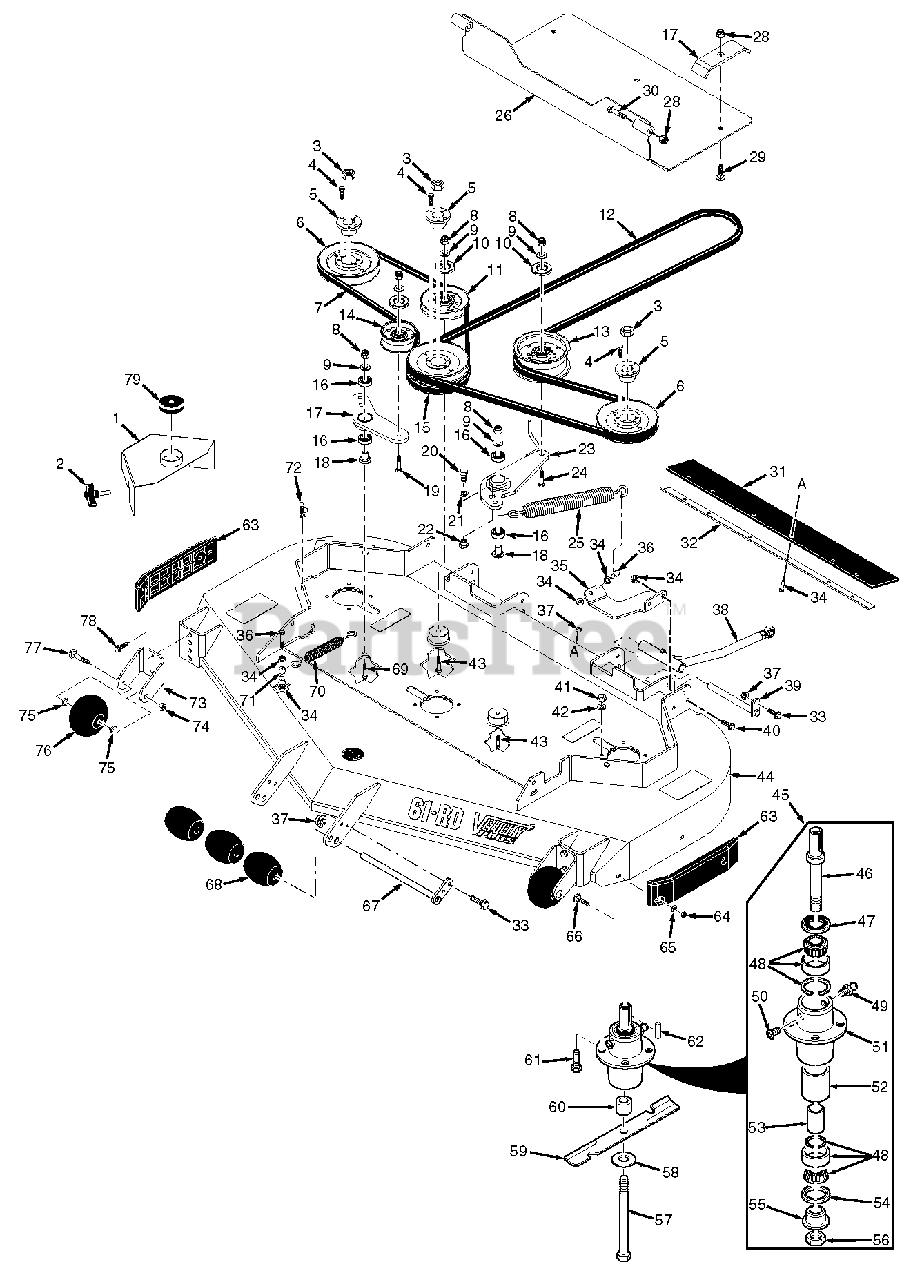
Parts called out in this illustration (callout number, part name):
1	Belt Cover, 61V
2	Knob w/Stud
3	Nut, 5/8-11 UNC
4	Bolt, Hex Head 1/4-20 x 1"
5	Tapered Hub, 1.125" Bore
6	Pulley, 6.32" Dia.
8	Nut, Elastic Stop 3/8-16
9	Flatwasher, 3/8-.391 x .938 x .105
10	Dust Shield
11	Pulley, Idler
12	Belt, Deck Drive
13	Pulley, 5" Idler
14	Pulley, 3-1/2" Idler
15	Pulley, 6.32" Dia. Double Groove
16	Bearing
17	Idler Arm Assy.
18	Pivot, Idler
19	Bolt, Hex Head 3/8-16 x 2-1/2"
20	Bolt, Hex Head 7/16-14 x 1"
21	Lockwasher, 7/16" Spring
22	Boss, Spring Anchor
23	Idler Arm Assy.
24	Bolt, Hex Head 3/8-16 x 3"
25	Spring, LH Cutter Deck
26	Weldment, Debris Shield
27	Mounting Bracket, Shield
28	Nut, Elastic Stop 5/16-18
29	Bolt, Carriage 5/16-18 x 1-1/2'
30	Bolt, Hex Head 5/16-18 x 2-3/4"
31	Pad, Rubber
32	Retaining Plate, Pad
33	Bolt, Hex Head 5/16-18 x 1"
34	Nut, Serrated Flange 3/8-16
35	Spring Mount, SMCZ
36	Bolt, Hex Head 3/8-16 x 1-1/2"
37	Nut, Elastic Stop 5/16-18
38	Pusharm Assembly, LH
38	Pusharm Assembly, RH
39	Rod Weldment, Pusharm
40	Bolt, Hex Head 3/8-16 x 1"
41	Nut, Elastic Stop 5/16-18
42	Lockwasher, 5/16"
43	Bolt, Hex Head 3/8-16 x 3"
44	Cutter Deck Assembly w/Decals SCZ-61RD
45	Spindle Assembly
46	Shaft, Spindle
47	Seal, Top
48	Bearing Assembly
49	Grease Fitting
50	Relief Fitting, Spindle
51	Spindle Housing
52	Spacer, Outside
53	Spacer, Inside
54	Seal, Bottom
55	Spindle Bushing
56	Nut, Special 1-1/16 - 18
57	Bolt, Hex Head 5/8-11 x 9-1/2"
58	Flatwasher, 5/8-.688 x 1.75 x .134 HD
59	Cutter Blade, 21"
60	Spacer, Spindle Bottom
61	Bolt, Hex Head 5/16-18 x 1-3/4"
62	Key, 1/4 x 1/4 x 2"
63	Wear Pad
64	Nut, Center Lock 5/16-18
65	Flatwasher, 5/16-.344 x .688 x .065
66	Bolt, Carriage 5/16-18 x 3/4"
67	Shaft Weldment
68	Wheel, Anti-Scalp
69	Bolt, Hex Head 3/8-16 x 2-1/4"
70	Deck Spring
71	Spacer
72	U-Nut, 3/8-16
73	Bracket, Anti-Scalp Wheel
74	Nut, Center Lock 3/8-16
75	Bushing, .376 I.D. Oilite
76	Wheel, Anti-Scalp
77	Bolt, Carriage 3/8-16 x 4"
78	Bolt, Hex Head Serrated Flange 3/8-16 x 1"
79	Cap, Spindle
